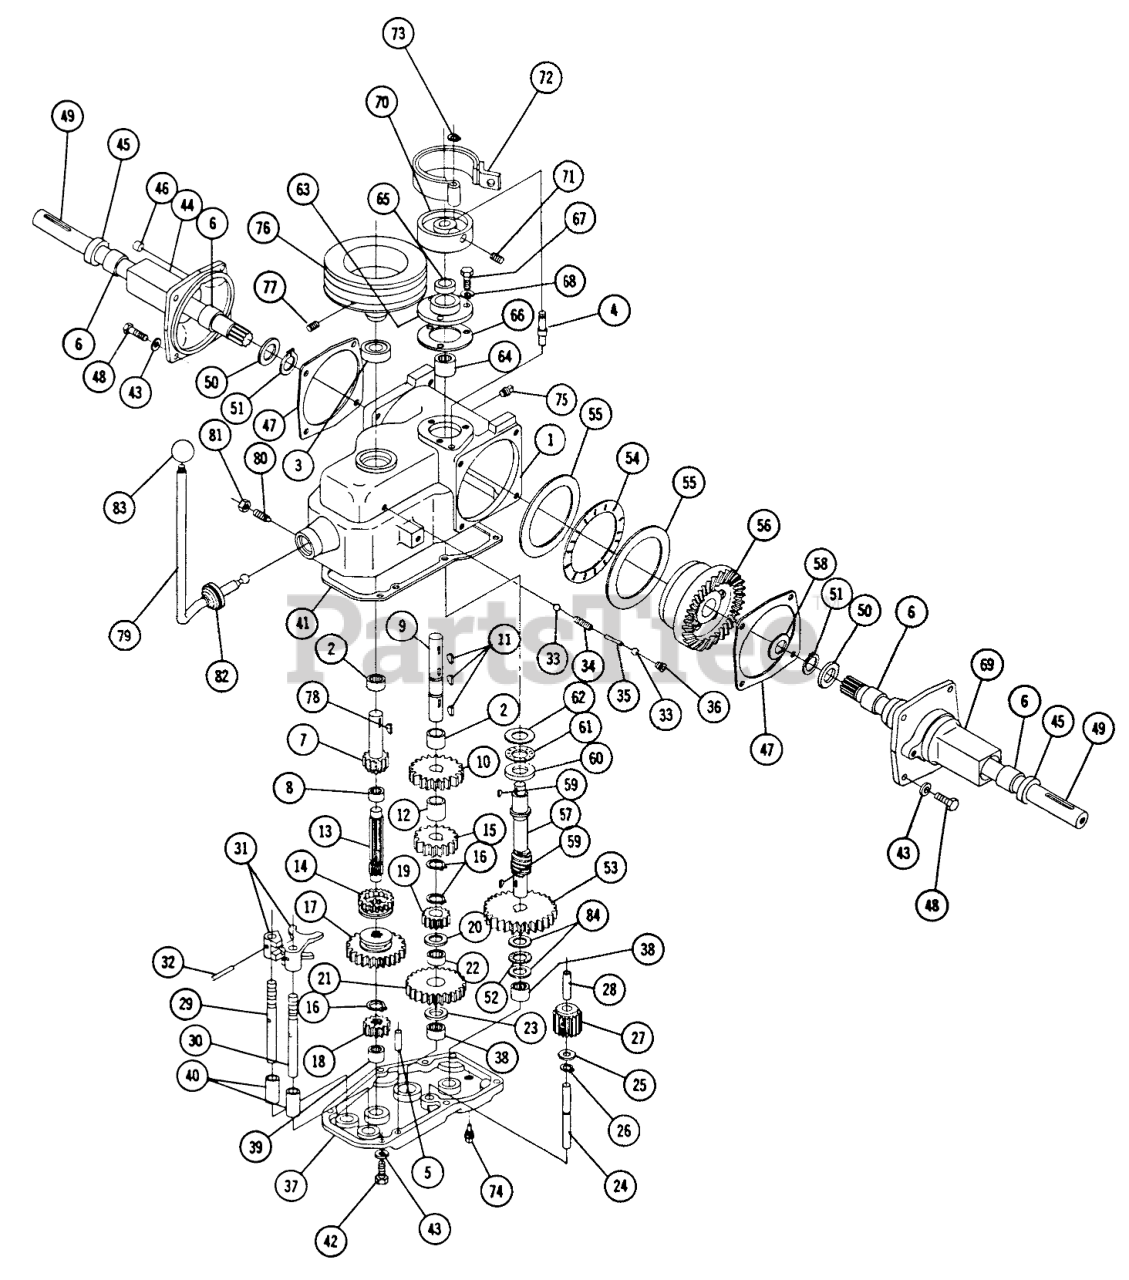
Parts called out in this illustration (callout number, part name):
1	Housing-Gear Case
2	BEARING-NEEDLE
5	PIN-DOWEL
6	BEARING-NEEDLE
8	BEARING-NEEDLE
9	Shaft Idler
18	GEAR
19	Gear-1st Speed
20	WASHER-THRUST
22	BEARING-NEEDLE
24	Shaft-Reverse Idler
25	RACE THRUST
27	GEAR/BUSHING ASM-REVERSE IDLER
28	BUSHING
29	RAIL-SHIFT
30	RAIL-REAR SHIFT
32	Roll Pin 1/8 x 1
33	BALL-DETENT
35	PIN-SHIFT
38	BEARING-NEEDLE
40	Bushing-Shifter Rail
42	Bolt 3/8-16 x 1
43	Lockwasher
48	Bolt 3/8-16 x 1
56	BULLT 325
59	KEY WOODRUFF
62	Rae-Thrust
67	Bolt 5/16-18 x
68	Lockwasher
69	Housing Axle L.H.
71	Screw 1/4-20 x 5/8
74	Plug 1/4 Pipe
77	Set Screw-Nylok
78	Key
80	SETSCREW
81	Nut 1/4-20
